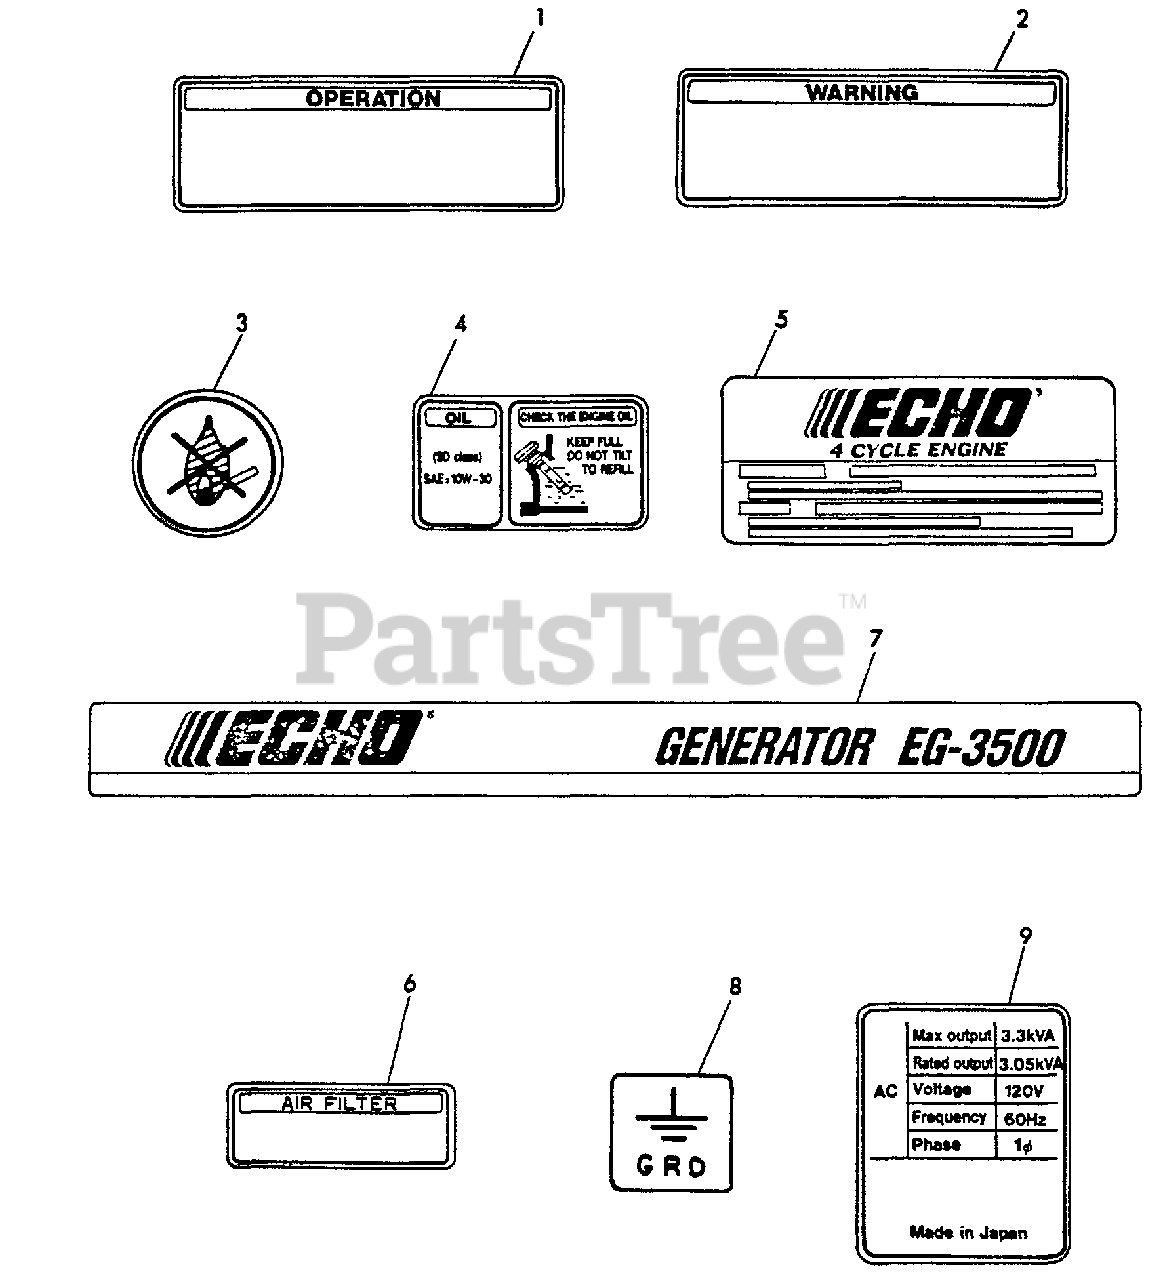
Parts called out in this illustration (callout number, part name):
1	LABEL
2	LABEL - WARNING
3	LABEL, NON FIRE
4	LABEL, OIL
5	LABEL - ECHO
6	LABEL - AIR FILTER
7	LABEL - MODEL EG3500
8	LABEL, EARTH
9	LABEL - GENERATOR
